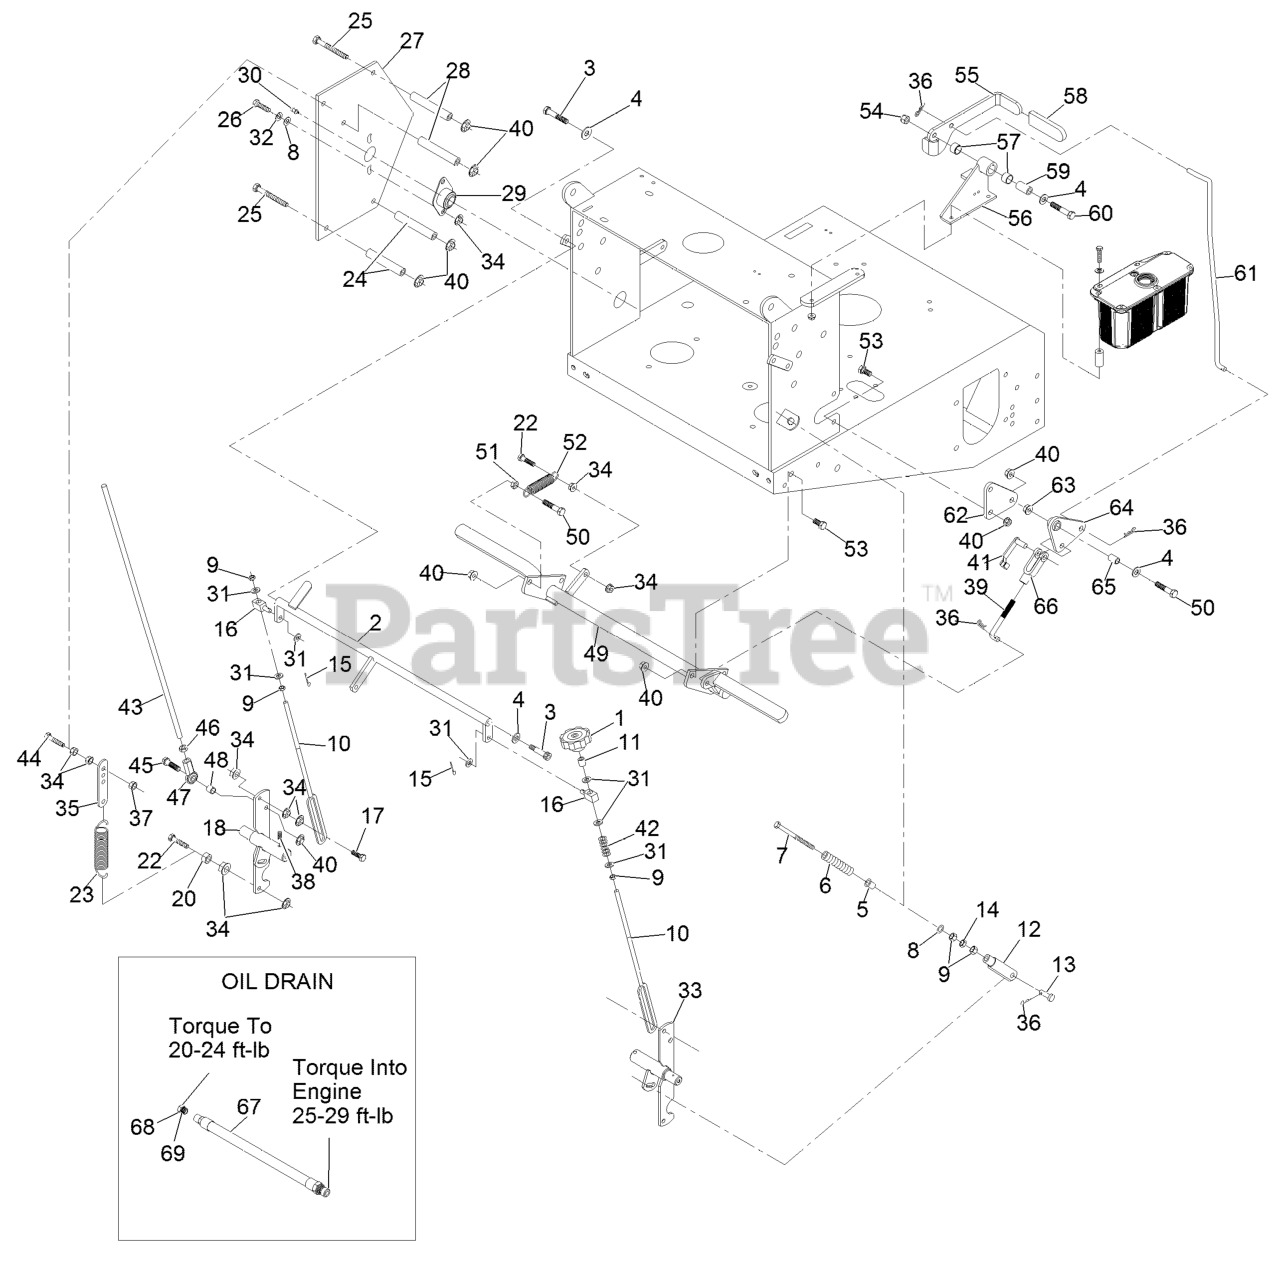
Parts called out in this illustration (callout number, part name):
1	KNOB-TRACKING
2	CRANK-CONTROL, SPEED
3	SCREW-HSH
4	WASHER-FLAT
5	BUSHING-FLANGED
6	SPRING,COMPRESSION (NEUT)
7	BOLT-RETURN, NEUTRAL
8	WASHER-FLAT
9	NUT-HEX
10	LINK-CONTROL, SPEED
12	YOKE-ADJUSTABLE
13	PIN-CLEVIS
14	NUT-JAM
15	PIN-COTTER
17	SCREW-HH
18	SHAFT-CONTROL, LH
20	NUT-JAM
22	SCREW-HH, SPECIAL
23	SPRING-EXTENSION
24	SPACER-SHIELD
25	SCREW-HH
26	SCREW-HH
27	SHIELD-CONTROL
28	SPACER-SHIELD
29	BEARING-FLANGE, SIDE
30	FITTING-GREASE
31	WASHER-PLAIN
32	WASHER-LOCK
33	SHAFT-CONTROL, RH
35	TAB-SPRING, EXTENSION
36	PIN-COTTER
37	NUT-LOCK, NI
38	SCREW-SET
39	LINKAGE-LOWER
40	NUT-HHF, WHIZ
41	PIN-SPRING, CLEVIS
42	SPRING-COMPRESSION
43	LINKAGE,DRIVE (PLT)
44	BOLT-TAP, HH
45	SCREW-HH
46	NUT-HEX JAM, LH
47	JOINT-BALL END, LH
48	SPACER-TUBE, PUMP LINK
50	SCREW-HH
51	NUT-JAM
52	SPRING-IDLER
53	SCREW-HH
54	NUT-LOCK, NI
55	LEVER,PARK BRK W/DECAL
56	BRACKET ASM
57	SLEEVE-BUSHING
58	GRIP-LEVER
59	BUSHING-PIVOT
60	SCREW-HH
61	LINKAGE-UPPER
62	BELLCRANK
64	BELLCRANK ASM
65	BUSHING-PLASTIC
66	YOKE-LINKAGE, BRAKE
67	ASM, ENGINE OIL DRAIN HOS
68	PLUG-HH
69	O-RING
